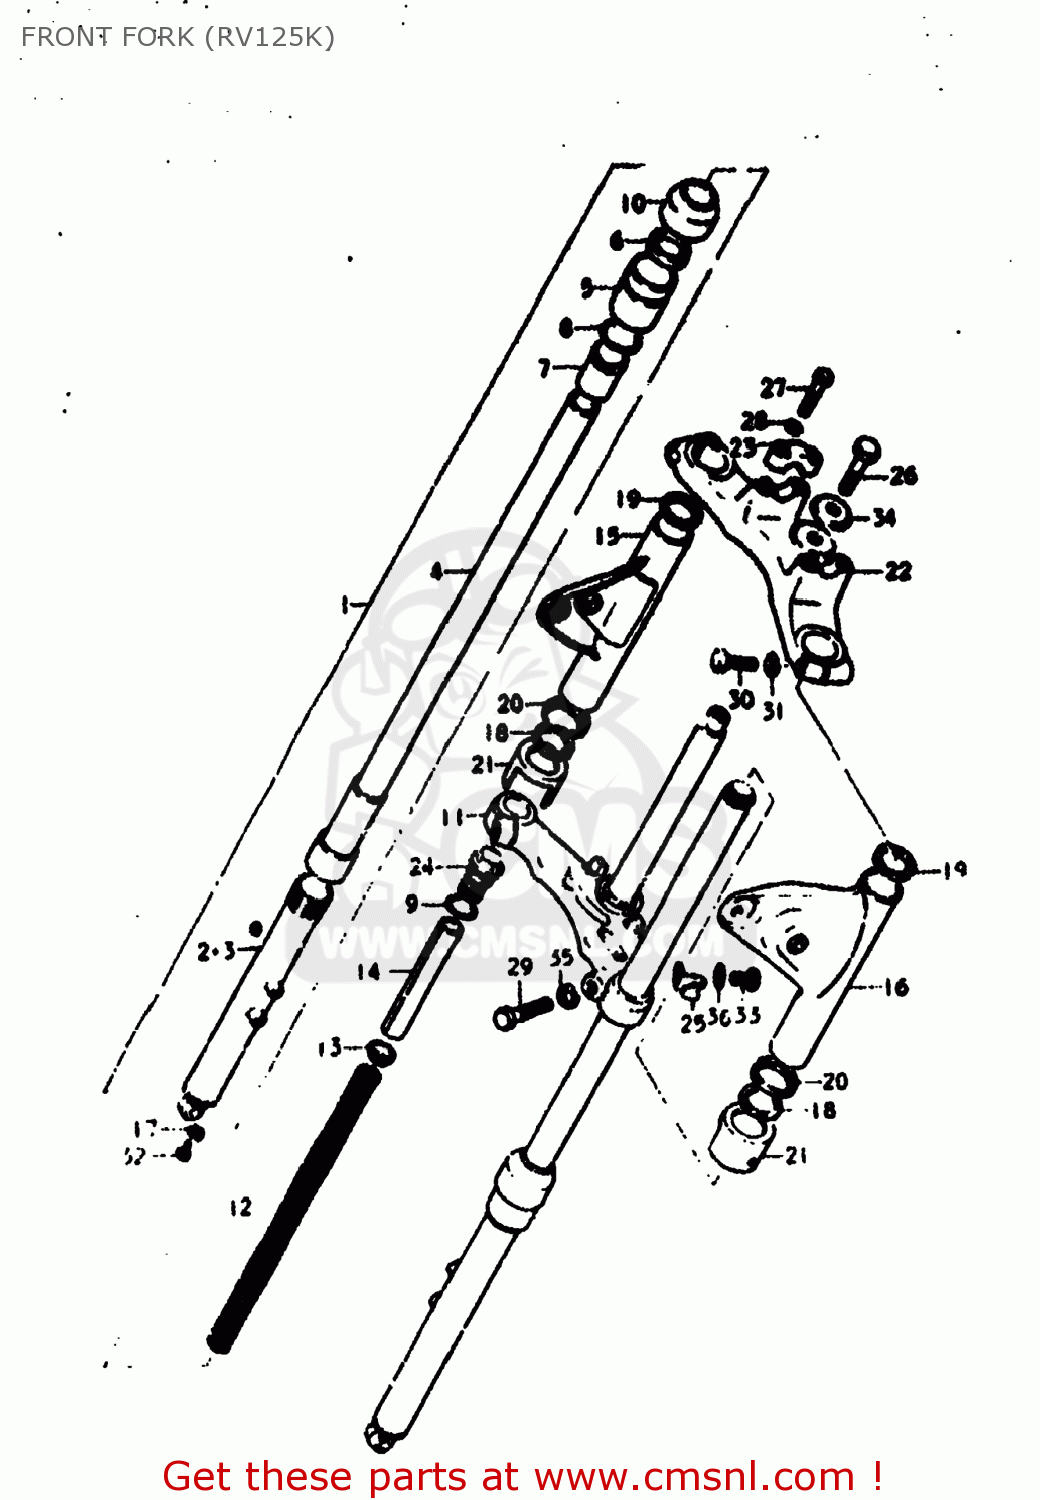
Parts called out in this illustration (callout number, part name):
1	DAMPER SET
2	TUBE,OUTER,RIGHT
3	TUBE,OUTER,LEFT
4	TUBE,FORK,INNER
5	NUT,FORK OUTER TUBE
6	SEAL,OIL
7	BUSHING,GUIDE
8	O RING,OIL SEAL LWR
9	O-RING,FORK INNER TUBE
10	SEAL,DUST
11	STEM,STEERING
12	SPRING,FRONT FORK
13	GUIDE,SPRING
14	SPACER,SPRING
15	BRACKET,HEADLAMP HOUSING
16	BRACKET,HEADLAMP,LEFT
17	GASKET,DRAIN,PLUG (NAS)
18	CUSHION,HEADLAMP BRACKET
19	SEAT,HEADLAMP BRACKET
20	SEAT,HEADLAMP BRACKET
21	CUSHION,HEADLAMP BRACKET
22	HEAD,STEERING STEM
23	HOLDER,HANDLEBAR
24	BOLT,FR FORK
25	CLIP,BRAKE CABLE
26	BOLT,FORK INNER TUBE
27	Bolt
28	WASHER,LOCK,8.
29	BOLT,FORK INNER TUBE F
30	BOLT,FORK INNER TUBE F
31	LOCK WASHER
32	SCREW
33	SCREW
34	WASHER
35	WASHER,LOCK 12
36	LOCK WASHER
